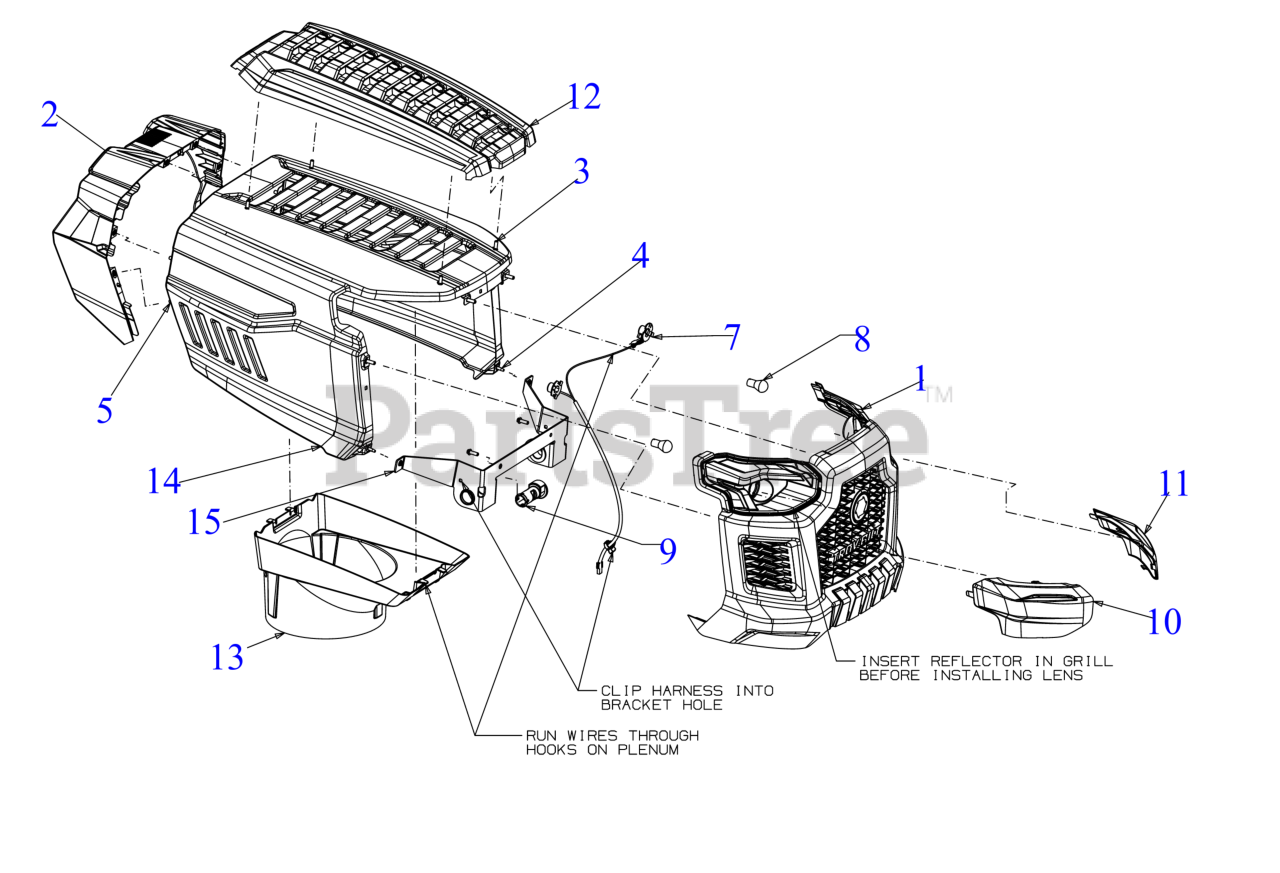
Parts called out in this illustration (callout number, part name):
1	FRONT GRILLE
2	DASH COLLAR ASSEMBLY
3	SCREW 1/4 x .750
4	SCREW M6-1 x .625
5	SCREW 1/4-20X.5 GR5
7	HEADLIGHT HARNESS
8	MINIATURE LAMP-12V #1156
9	HOOD PIVOT PIN
10	HEADLIGHT LENS (RH)
11	HEADLIGHT LENS (LH)
12	HOOD SCOOP
13	HOOD PLENUM (B STYLE)
